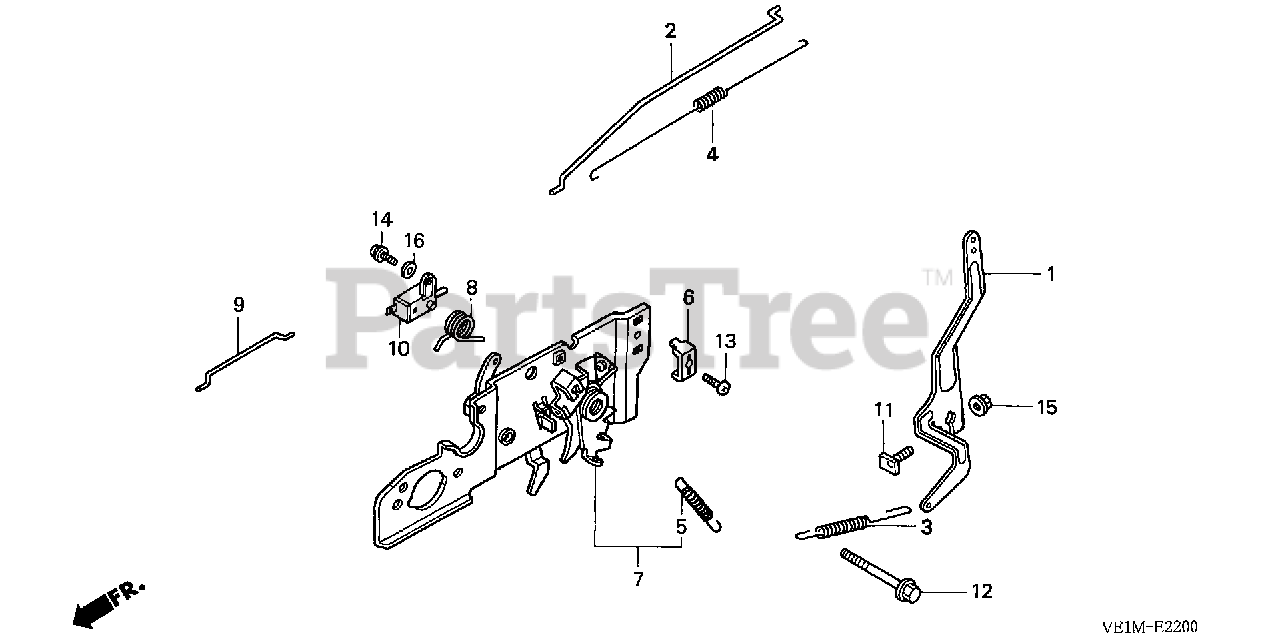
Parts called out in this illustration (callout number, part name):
1	ARM, GOVERNOR
2	ROD, GOVERNOR
3	SPRING, GOVERNOR
4	SPRING, THROTTLE RETURN
5	SPRING, LEVER
6	HOLDER, CABLE
7	BASE, CONTROL
8	SPRING, CONTROL LEVER RETURN
9	ROD, CHOKE
10	SWITCH ASSY., ENGINE STOP (N.O)
11	BOLT, GOVERNOR ARM
12	BOLT, FLANGE (6X45) (CT200)
13	SCREW, PAN (5X16)
14	SCREW-WASHER (4X12)
15	NUT, FLANGE (6MM)
16	WASHER, PLAIN (4MM)
17	HOLDER, CABLE
